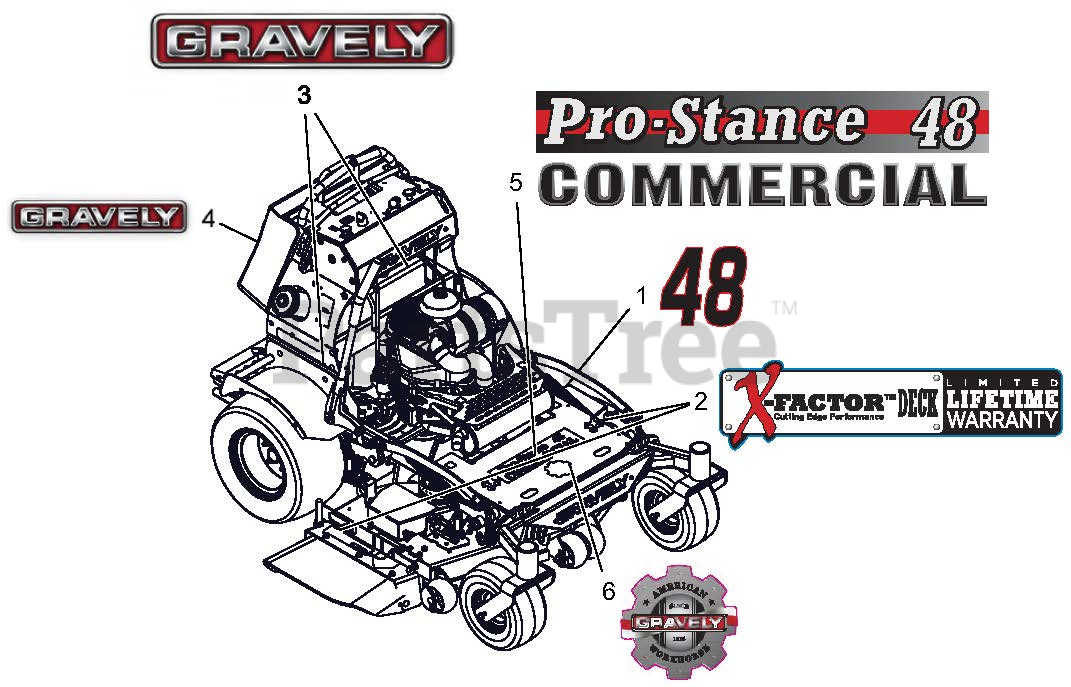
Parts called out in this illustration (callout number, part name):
1	DECAL, 48"
2	DECAL, X-FACTOR DECK
3	DECAL, 9.5" GRAVELY LOGO
4	DECAL, FUEL TANK-GRAVELY
5	DECAL, PROSTANCE 48"
6	DECAL, GRAVELY HERITAGE-LARGE
